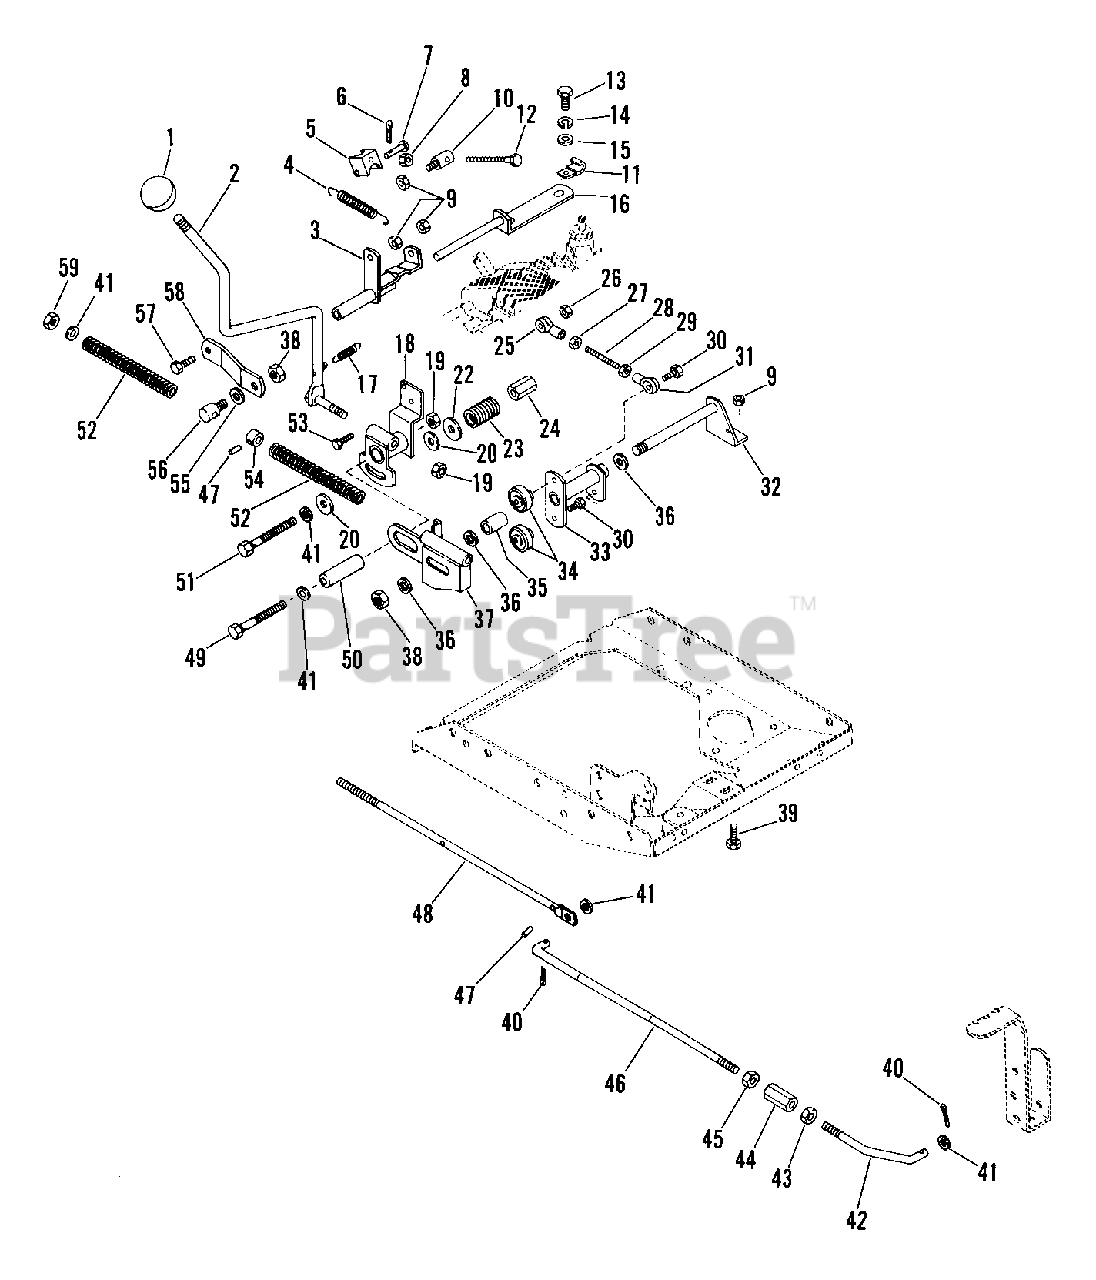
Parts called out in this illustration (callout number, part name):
2	SHIFT HANDLE
3	BRAKE TUBE
4	SG-TENS .091X.56X4.25 WLD 40
6	PIN-COTR .09X.75 PL
7	PIN, CLEVIS .243/.248X1.50 YWZ
8	NUT-HEX .312-18
9	NUT-LK .312-18 GR A PL
10	ROD PIVOT
11	J-CLAMP
12	BLT-HEX .31-18X3.50 PL GR2
13	BLT-HEX .31-18X.63 PL GR 2
14	WSHR-LK-EXT .313X.030 PL
15	WSHR-FL-STL.312X.734X.065PL
16	BRAKE BRACKET
17	SG-TENS .063X.44X1.56
19	NUT-LK-CTR .375-16 GR A PL
20	FRICTION WASHER
22	WSHR-FL-STL .406X1.125X.125 PL
23	SG-COMP .120X.74X2.09 PL
24	NUT GUIDE .375-16 PL
25	ROD END, 1/4 LH
26	NUT-LK-CTR .250-20 PL
27	NUT-LH .250-28 GR2 PL
29	NUT-HEX .250-28 YWZC
30	BLT-HEX .25-28X.75 PL GR5
31	ROD END, 1/4 RH
32	PIVOT-BRAKE
33	SHIFT CONTROL
34	BRG-BALL .25-28X1.375X.72
35	SPACER .512X.748X1.16
36	WSHR-FL-STL .505X.880X.072 PL
37	BRAKE BRACKET
38	NUT-LK-CTR .50-13
39	BLT-RDHDSQNK .312-18X.62SHTPL
40	PIN-COTR .12X.75 PL
41	WSHR-FL-STL.406X.812X.065PL
42	FRT BRAKE ROD
43	NUT-HEX .375-16
44	NUT-CUPLG RH & LH THD .37-16PL
45	NUT LH THD .375-16 GR 2 PL
46	REAR BRAKE ROD
47	PIN-ROLL .125X.63
48	BRAKE ROD
49	BLT-HEX .38-16X3.25 PL GR5
50	SPACER .411X.750X2.465
51	BLT-HEX .38-16X3.25 PL GR2
52	SG-COMP .125X.74X6.27 WLD 85
53	BLT-HEX .25-20X.75 PL GR2
54	LOCATOR BUSHING
55	WSHR-FL-STL .520X.810X.033
56	UNIVERSAL ROD ADAPTER
57	BLT-HEX .31-18X1.00 PL GR 2
58	BRAKE LINK
59	NUT-LK-NYL .375-24 PL
